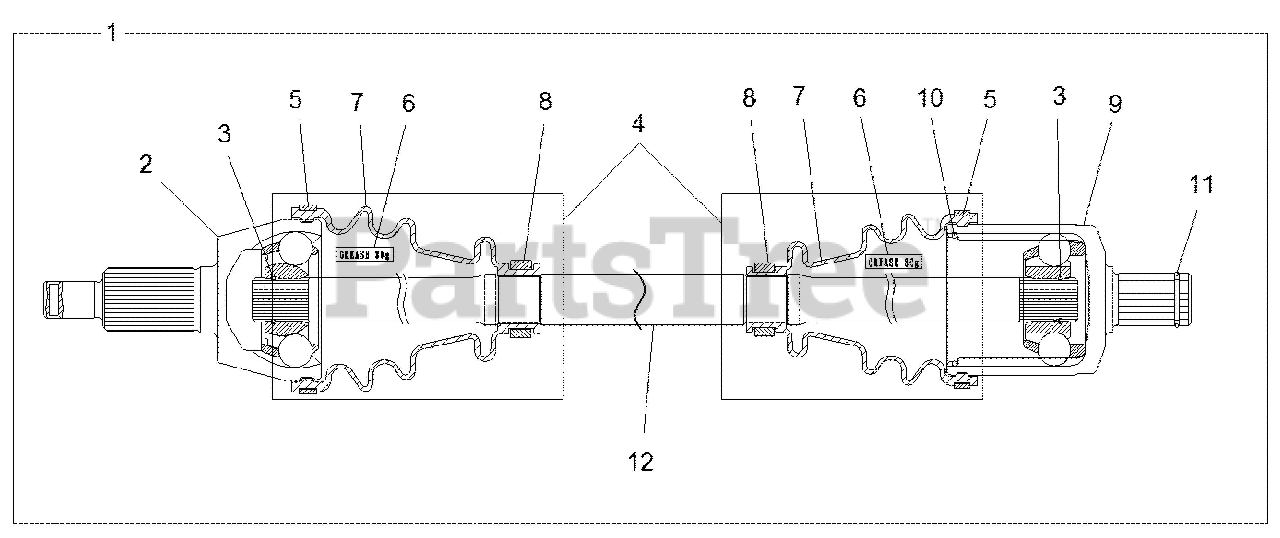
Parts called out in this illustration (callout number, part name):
1	ASM-HALF SHAFT,FRONT,LT
2	JOINT-CV,OUTER
3	CIRCLIP-1.8X22.2(PR-3011)
4	KIT-BOOT,PLUNGING JNT(PR-8062)
5	CLAMP-LARGE(PR-2019)
6	GREASE(K575/VW738)
7	BOOT(PR-0015)
8	CLAMP-SMALL(PR-0016)
9	JOINT-CV,INNER
10	CIRCLIP-2.0X61.7(PR-2016)
11	CIRCLIP-1.6X24.4(PR-2025)
12	SHAFT,23.5(PR-315)
